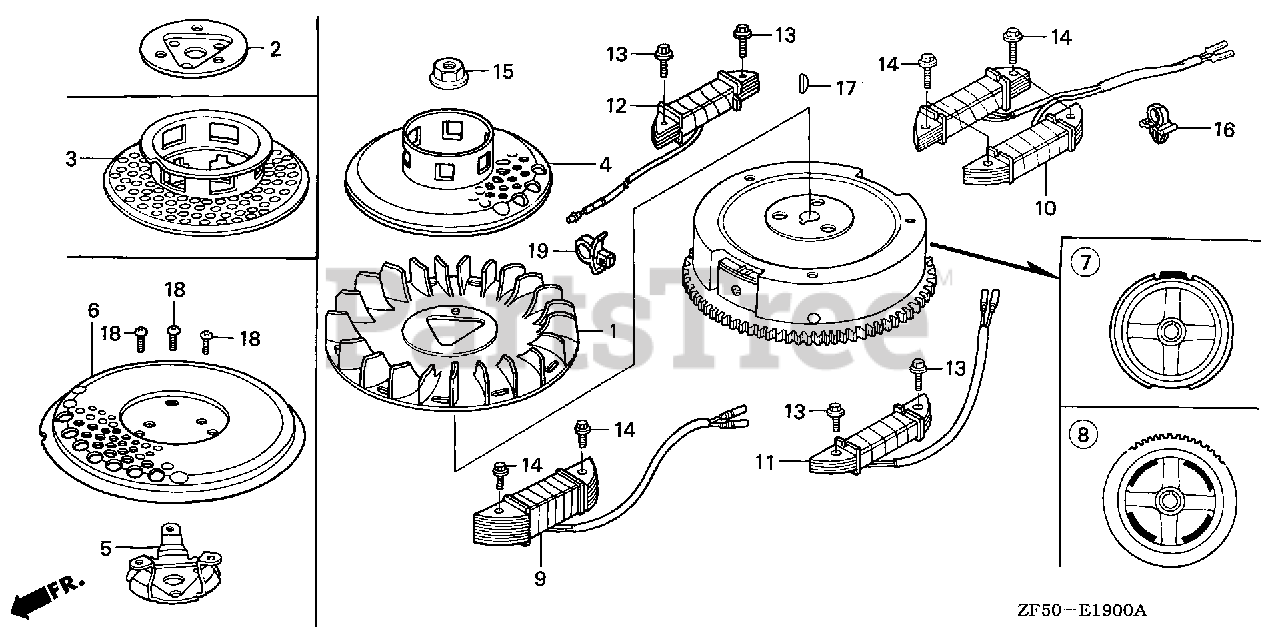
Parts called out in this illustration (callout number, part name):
1	FAN, COOLING
3	PULLEY, STARTER Use up to Engine SN 2013098.
4	PULLEY, STARTER (SCREEN GRID)
7	FLYWHEEL Use up to Engine SN 1000149.
7	FLYWHEEL
15	NUT, SPECIAL (16MM)
17	KEY, SPECIAL WOODRUFF (25X18)
